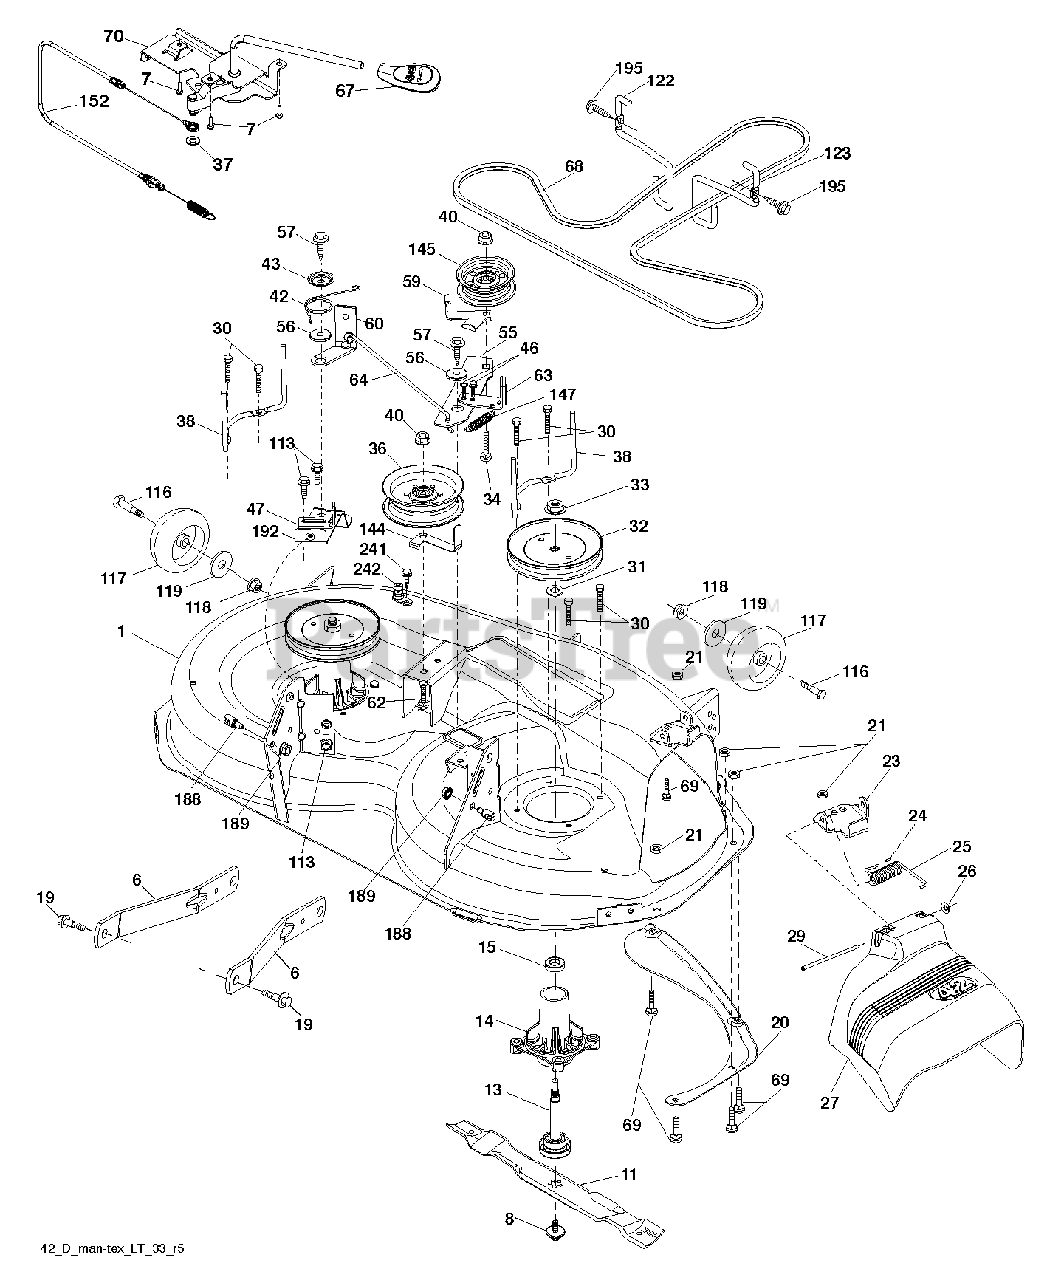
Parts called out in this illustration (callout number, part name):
1	DECK.WELDMENT.42"
6	ARM.SUSPENSION.MOWER.R
7	SCREW.#10 X 0.750.BOS THREAD
8	BOLT.WASHER.ASM.7/16-2
11	42" HI-LIFT BLADE
13	SHAFT.ASM.MDRL.N/GREASE.38
14	HOUSING MANDREL
19	BOLT.SHOULDER
20	BAFFLE.VORTEX
21	LOCKNUT
23	BRKT.DEFLECTOR.38"2005+
24	CAP-SLEEVE LT
25	SPRING.TORSION.DEFLECT
26	NUT PUSH M
27	SHIELD.DEFLECTOR.MOWER.42"BLAC
29	ROD.HINGE
30	SCREW, WASHER HEAD
31	WASHER.SPACER.MANDREL
32	PULLEY.MANDREL.5.438.PD
33	NUT.FLANGE.LOCK.TOP
34	BOLT.3/8-16X1.50
36	PULLEY.IDLER.2006
38	KEEPER.BELT.MANDREL.PULLEY
40	NUT LOCK FLG 3/8-16 UNC
42	SPRING.TORSION.BRAKE
43	SRPING.TORSION.RETAINE
46	SCREW.1/4-20X5/8
47	BRKT.CLUTCH.CABLE
55	IDLER.ARM.42"
56	SPACER.RETAINER
57	SCREW 3/8-16X1
59	GUARD, BELT
60	ARM BRAKE MOWER
62	BOLT
63	ARM BRAKE MOWER
64	LINK BRAKE
67	HANDLE.CLUTCH.CABLE.LT
68	BELT.DECK.DRIVE.42"
69	BOLT
70	CLUTCH.ASM.MANUAL.LT.PRED
113	BOLT.5/16HEX.WHS.HD
117	WHEEL.GAGE.HALF.SPOKED
118	NUT LOCK FLG 3/8-16 UNC
119	WASHER
122	KEEPER BELT ENGINE LH
123	KEEPER BELT RH
144	KEEPER.BELT.MOWER
145	PULLEY.IDLER.48"PRIMARY
147	RETURN SPRING
152	CABLE.CLUTCH.MANUAL.
188	STUD.FASTNER.W/ANTI-ROTATE
189	NUT LOCK HEX FLANGE 5/16-18
192	BRKT.BRAKE.STAND.LH.
195	SCREW, 3/8-16X3/4
242	PORT.WASHOUT
